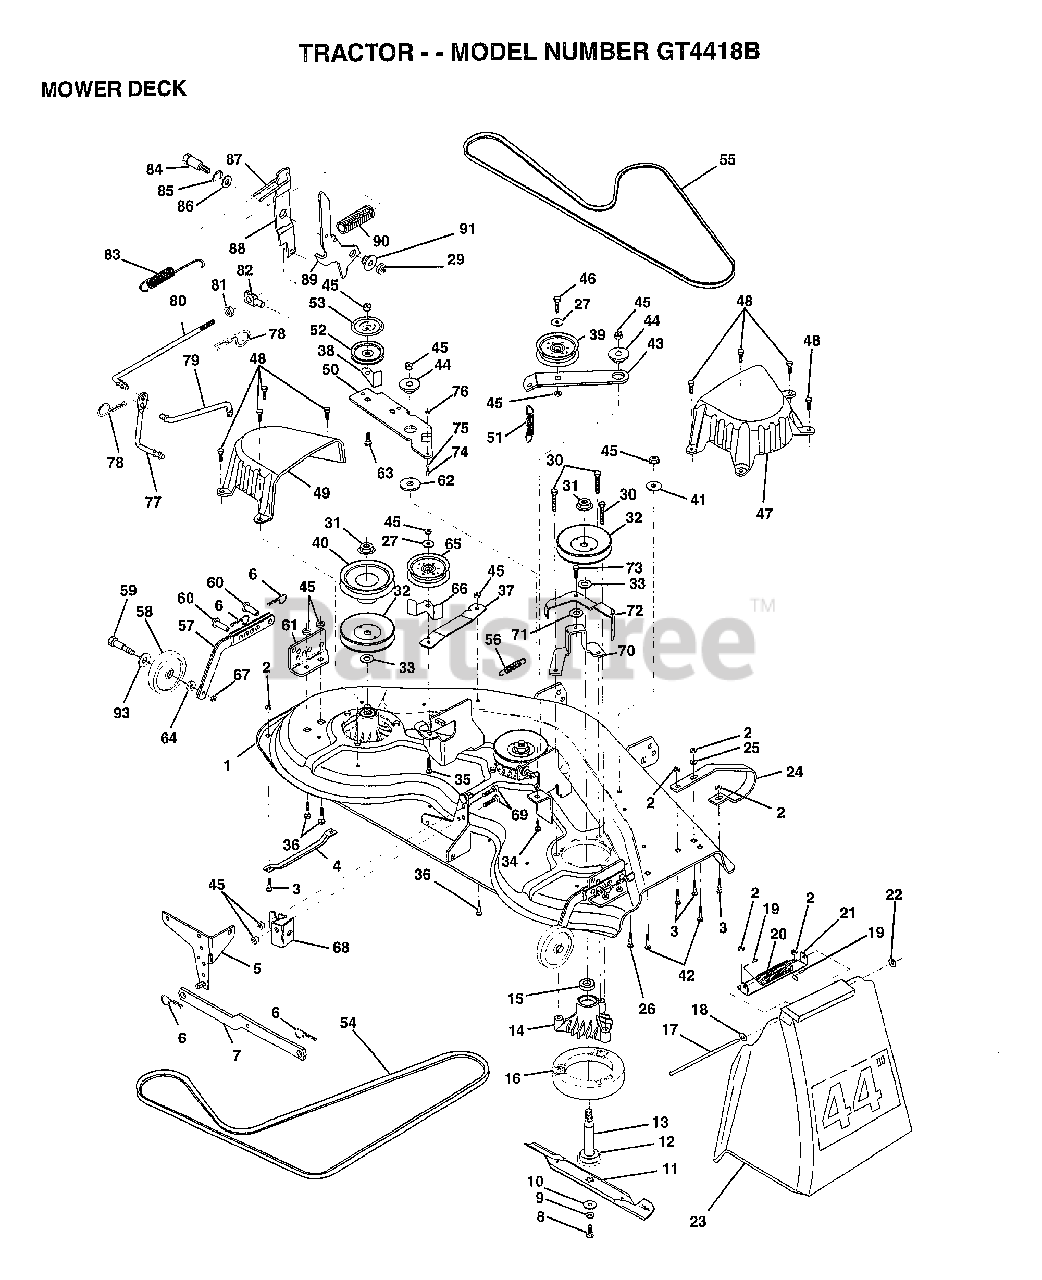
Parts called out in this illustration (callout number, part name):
1	"DECK ASM WELD44"""
4	RUNNER-LH M
5	BRKT.ASM.SW.44/50
8	BLADE BOLT
10	WASHER.HARD.BLADE
11	"BLADE.44"" HIPERF"
12	BEARING.BALL
13	SHAFT.ASM.W/BRNG
14	HOUSING.MAND.44.V
15	BEARING
16	STRIPPER RND MWR
17	ROD-HINGE T
18	WASHER
19	CAP-SLEEVE LT
20	SPRING TORSION
21	BRKT DEFLECTOR
22	NUT PUSH M
23	DEFLECTOR SHIELD
24	RUNNER.RH
25	WASHER M
26	BOLT
27	WASHER
33	WASHER
34	BOLT.3/8-14X1.25
35	BOLT
36	BOLT D
37	STIFFENER.ARM.IDL
38	KEEPER BELT IDLER
39	FLAT IDLER PULLEY
40	"PULLEY.DRIVEN.44"""
42	BOLT
43	"ARM.IDLER.SEC.44"""
44	SPACER RETAINER
47	"COVER.MAND.RH.44"""
48	SCREW.1/4-20X5/8
49	COVER.MANDREL.LH
50	ARM.IDLER.PRIMARY
51	"SPRING.SEC.44""VEN"
52	PULLEY.IDLER.VGRO
53	SHIELD.IDLER.44.V
54	BELT-V MOWER PRIM
55	BELT-V.88.12.MW
56	"SPRING,EXTENTION"
57	BAR.ASM.GUAGE.WHL
58	WHEEL.GAGE.BLK.PL
59	BOLT M
60	PIN.CLEVIS
61	BRACKET.GUAGE.WHL
62	HARDENED WASHER
63	BOLT.3/8-16X1.50
64	WASHER
65	IDLER-FLAT T
67	LOCKNUT
68	BRACKET PVT MCH
70	"BRACKET SUPT 44"""
71	HARD SMALL WASHER
72	ARM BRAKE ASM
73	BOLT.SHLD.5/16-18
75	SHOULDER BOLT
76	LOCKNUT
77	PIVOT ROD
78	RETAINER M
79	ROD CLUTCH SECON
80	ROD.CLUTCH.PRIM44
81	NUT
82	TRUNION ADJ
83	SPRING EXT
84	SHOULDER BOLT
85	RING
86	WASHER
87	SPRING KEEPER
88	CLUTCH ARM SECOND
91	BUSHING
93	WASHER
